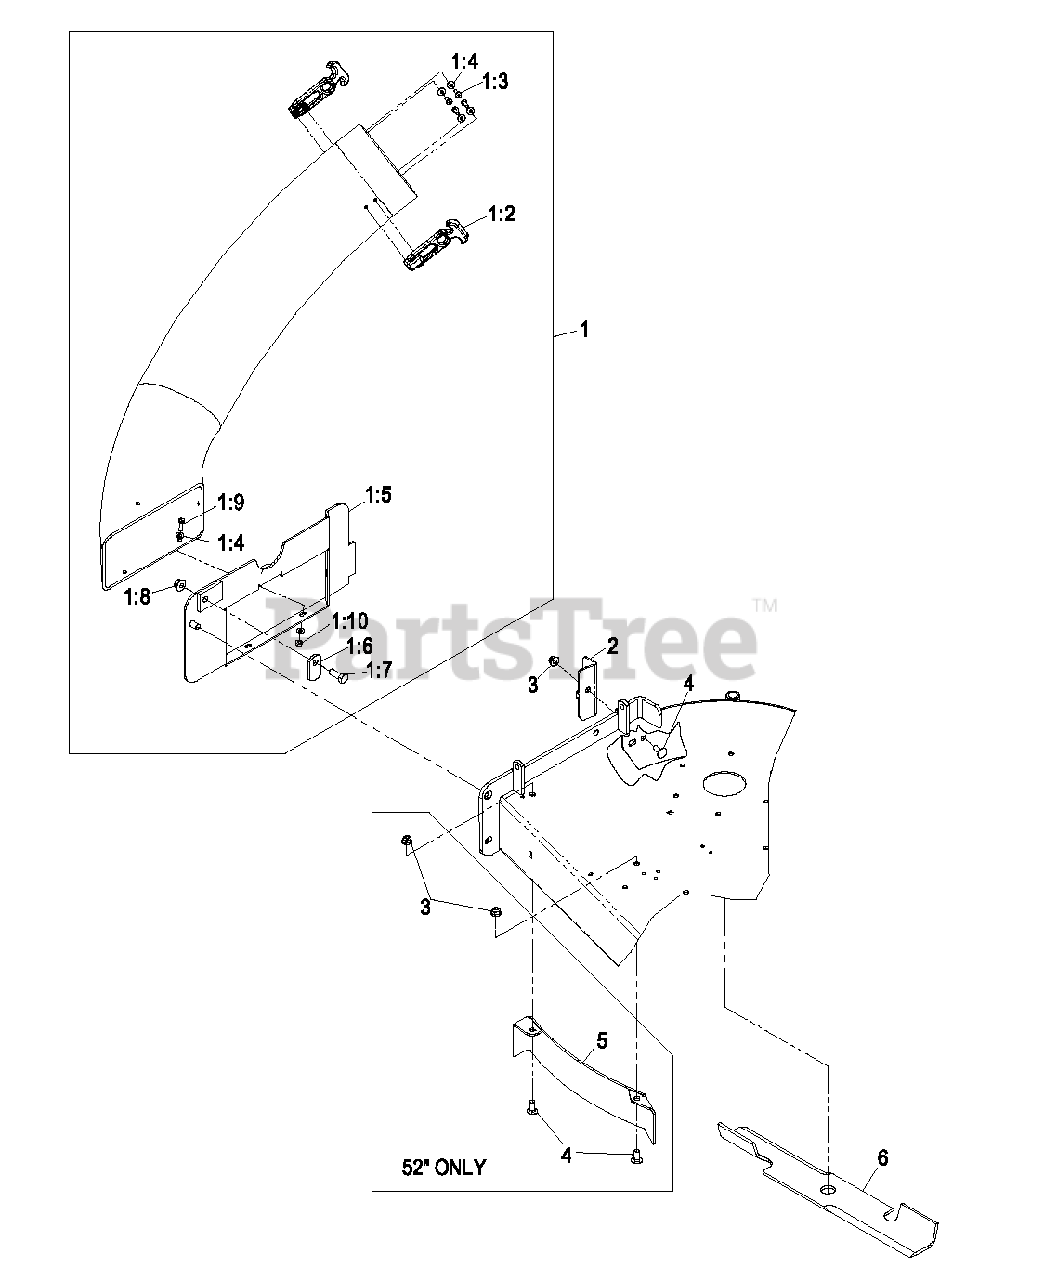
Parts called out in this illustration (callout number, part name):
1	TUBE AND STRAP ASM
1:2	LATCH-RUBBER
1:3	SCREW-PPH
1:4	WASHER-FLAT
1:5	BOOT FRAME ASM
1:6	LATCH-CATCHER, GRASS
1:7	SCREW-HH
1:9	SCREW-HWH
1:10	NUT-LOCK, NI
2	BRACKET-BOOT MOUNT, 52 IN
2	BRACKET-BOOT MOUNT, 48 IN
3	NUT-HF, NI
4	SCREW-CARR
5	BAFFLE-DISCHARGE, 52 INCH
6	Blade, 52" Bagger
